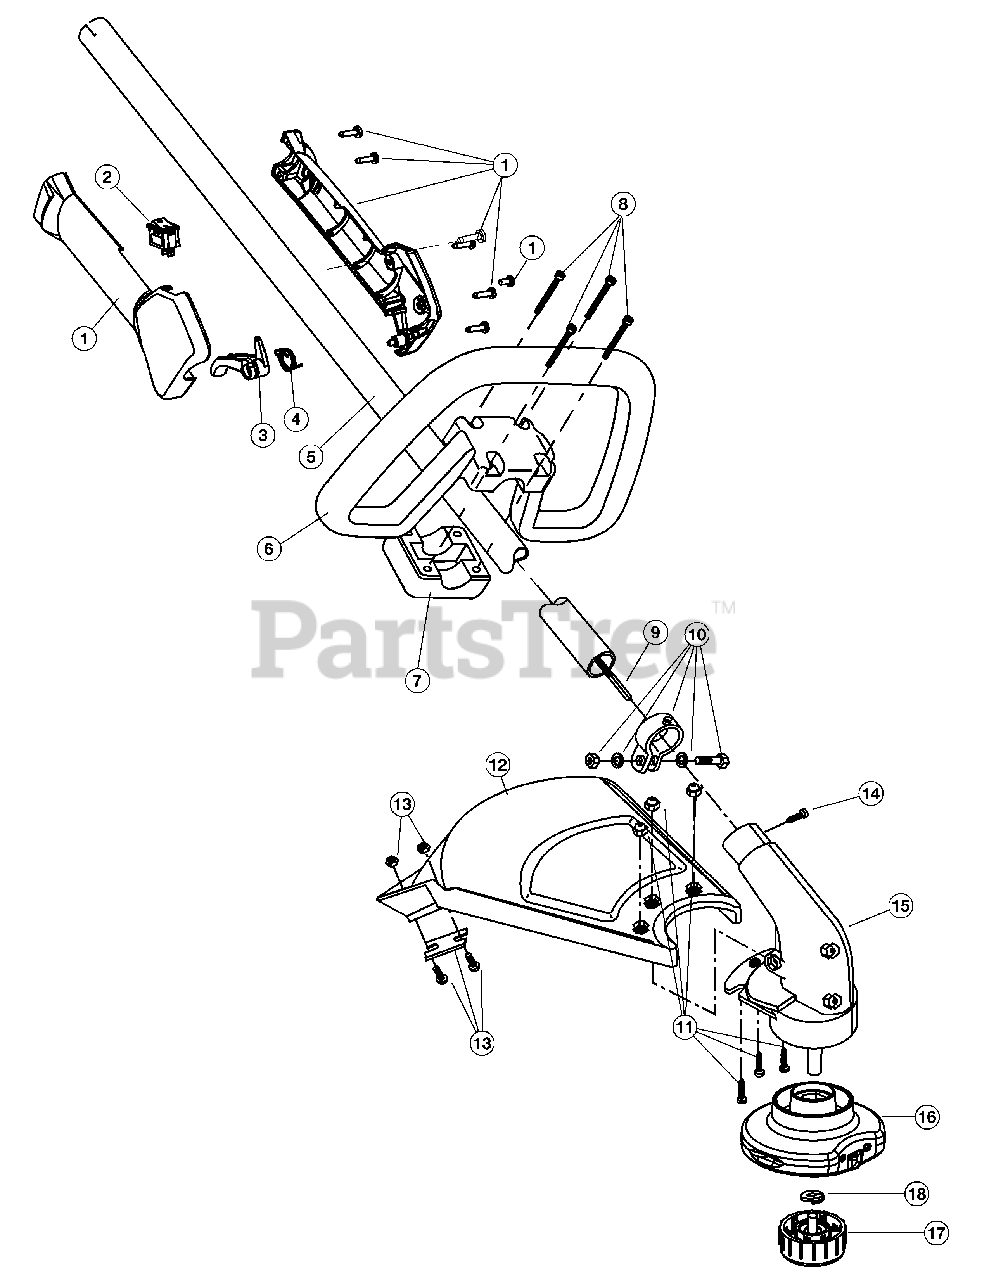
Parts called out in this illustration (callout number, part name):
1	Throttle Housing Assembly (includes 2-4)
3	Throttle Trigger
4	Throttle Trigger Spring
5	Drive Shaft Housing Assembly (includes 9)
6	D-Handle (includes 7&8)
7	D-Handle Base
9	Flexible Drive Shaft
10	Lower Clamp Assembly (includes 14)
11	Guard Mounting Screw Assembly
12	Guard Assembly (includes 13)
13	Blade Assembly
14	Anti-Rotation Screw
15	Gearbox Assembly
16	Fixed HD Line Assembly
17	Bump Head Knob Assembly
18	Lock Washer
